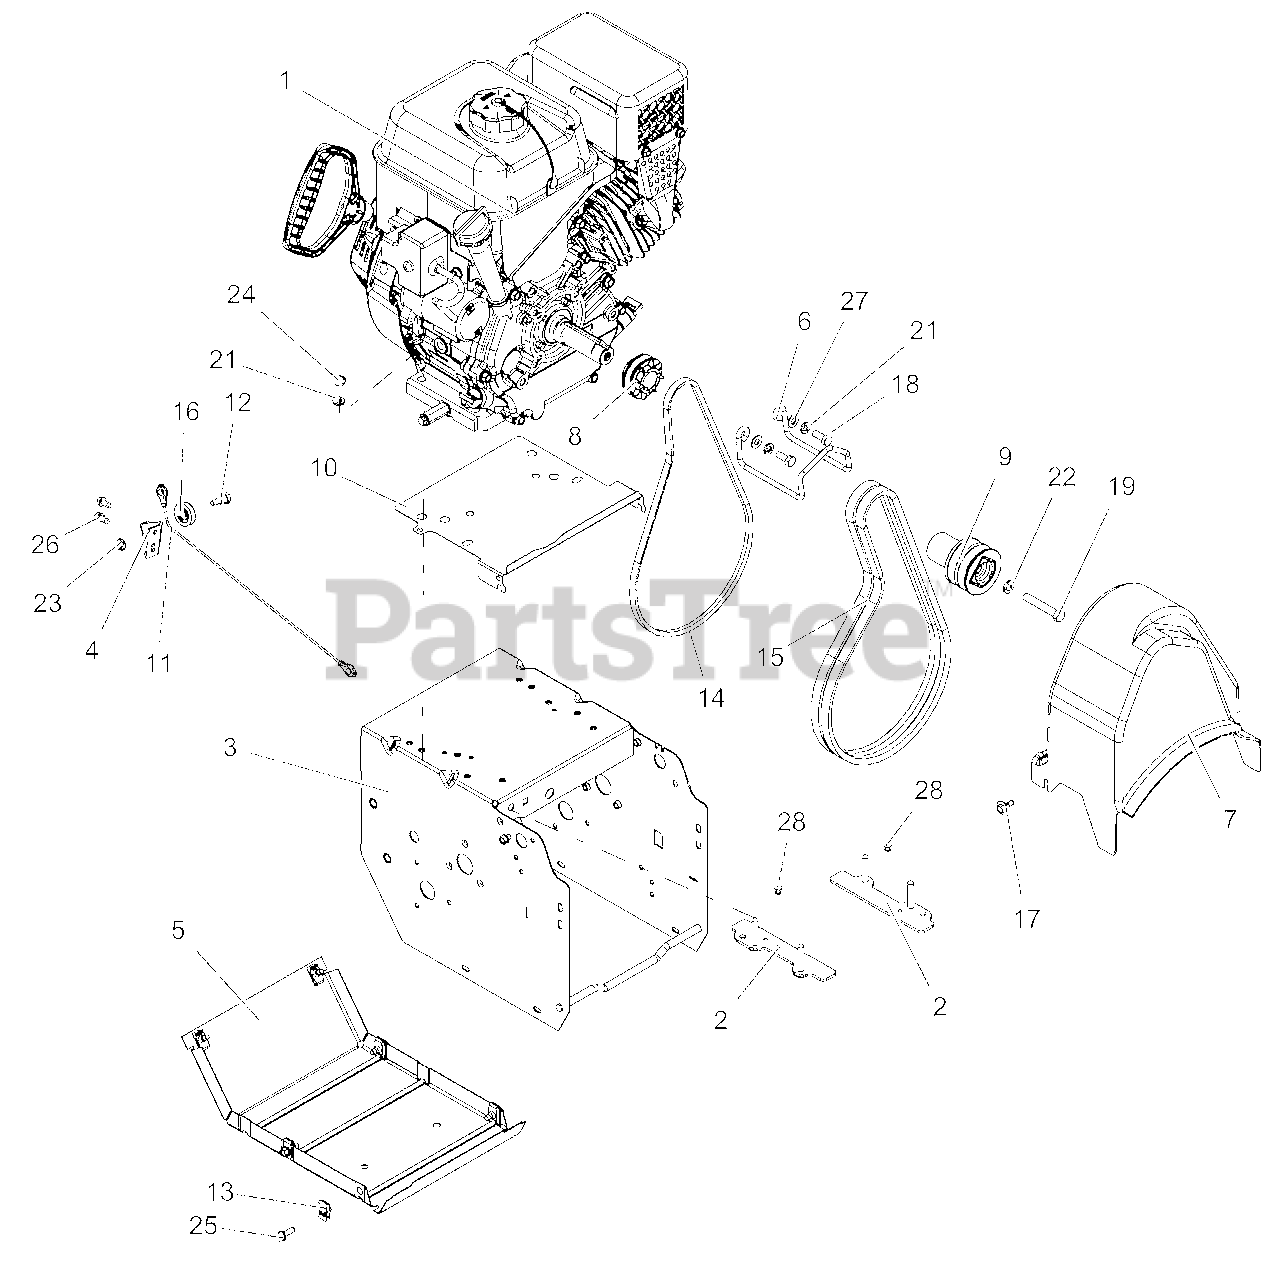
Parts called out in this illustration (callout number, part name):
1	ENGINE, ARIENS AX291 120V/60W
2	STRAP,ENGINE BOLT,ARIENS MED
3	WELDMENT, FRAME - DELUXE 16"
4	BRACKET, CABLE PULLEY
5	COVER, BOTTOM
6	FINGER, BELT
7	BELT COVER
8	SHEAVE, DRIVE
9	SHEAVE,ATTACHMENT 2-GRV
10	BAFFLE,ENGINE,ARIENS MED BLOCK
11	CABLE, LOWER TRACTION (DELUXE)
12	BOLT, SHLDR-.375X.375X.25-20
13	NUT-RTNR .25-20X.56
14	V-BELT, 3L-WRAPPED
15	V-BELT, HA-RAW EDGE (SET)
16	PULLEY, CABLE
17	SCR-TAP .25-20X.5 CAPTIVE
18	BLT-HEX .31-24X.75 YWZC GR5
19	BLT-HEX .38-24X2.25 YWZC GR5
21	WSHR-LK .312X.097 HVY YWZC
22	@WSHR-LK .38X.094 REG YWZC
23	@NUT-LK-CTR-FLG .25-20 YWZC
24	@NUT-HEX .31-18 YWZC
25	BLT-HEX .25-20X.75 HWH YZ GR5
26	SCR-TAP .25-20X.50 HWH TR YWZ
27	@WSHR-FL-STL.344X.688X.065YWZC
28	RVT-POP .187 YZ
